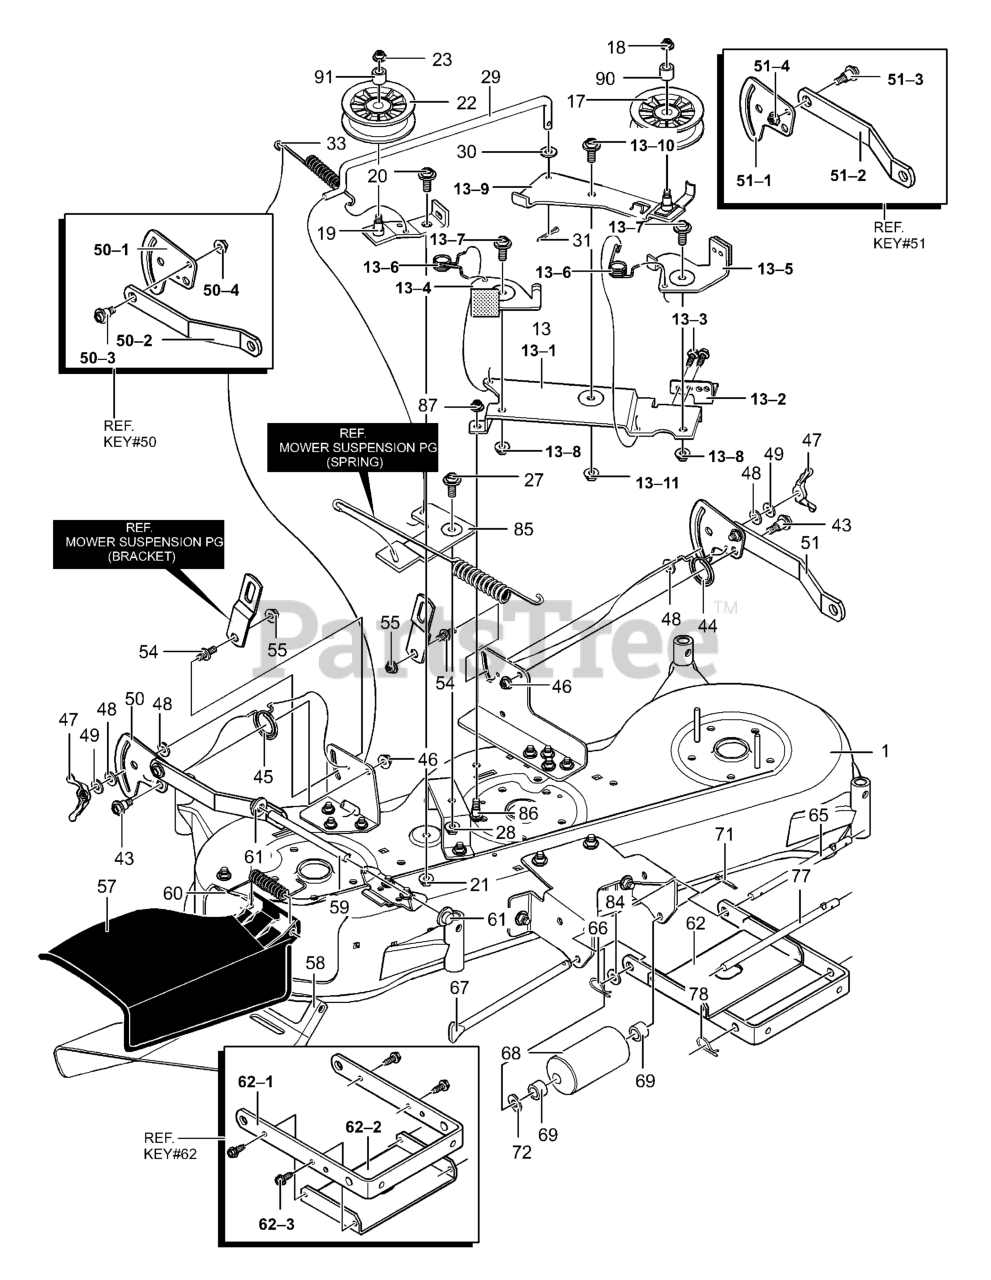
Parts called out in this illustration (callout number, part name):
1	46" MOWER DECK
13	BRACKET, MOUNTING
13-1	PLATE, BRAKE ARM
13-2	BRACKET, MOUNTING
13-4	ASSEMBLY, LEFT BRAKE
13-5	ASSEMBLY, BRAKE CENTER
13-6	TORSION SPRING
13-7	BOLT
13-8	LOCKNUT, FLANGE
13-9	ASSSEMBLY, IDLER ARM
13-10	BOLT
13-11	LOCKNUT, FLANGE
17	PULLEY, IDLER
18	NUT, 3/8-16
19	ASS'Y, RIGHT IDLER ARM
21	NUT 3/8-16
22	PULLEY, IDLER
23	NUT, 3/8-16
28	NUT, 3/8-16
29	LINK, BELLCRANK
30	WASHER, FLAT
31	PIN, COTTER
33	SPRING, EXTENSION
43	BOLT, SHOULDER
44	SPRING, TORSION
45	SPRING, TORSION
46	NUT, 3/8-16
47	WINGNUT, 5/16-18
48	PAD, FRICTION
49	WASHER
50	BRKT, RIGHT SUSPENSION
50-1	PLATE, SUSPENSION
50-2	BRKT, REAR SUSPENSION
50-3	BOLT, SHOULDER
50-4	LOCKNUT, FLANGE
51	BRKT, LEFT SUSPENSION
51-1	PLATE, SUSPENSION
51-2	BRKT, REAR SUSPENSION
51-3	BOLT, SHOULDER
51-4	LOCKNUT, FLANGE
54	PIN, HANGER
55	NUT, 3/8-16
57	DEFLECTOR, CHUTE
58	DEFLECTOR, INNER CHUTE
59	ROD, DEFLECTOR
60	SPRING, TORSION
61	NUT, PUSH CAP
62	BRACKET & STIFFENER
62-1	BRKT, FRONT SUSPENSION
62-2	STIFFENER
65	ROD, DECK
66	PIN, HAIR
67	ROD, ROLLER
71	PIN, COTTER
72	WASHER, WAVE
77	ROD, HANGER
78	PIN, HAIR
84	WASHER, FLAT
85	BELLCRANK
87	NUT, 5/16-18
90	SPACER 1/2 TO 17MM
91	SPACER 1/2 TO 17MM
